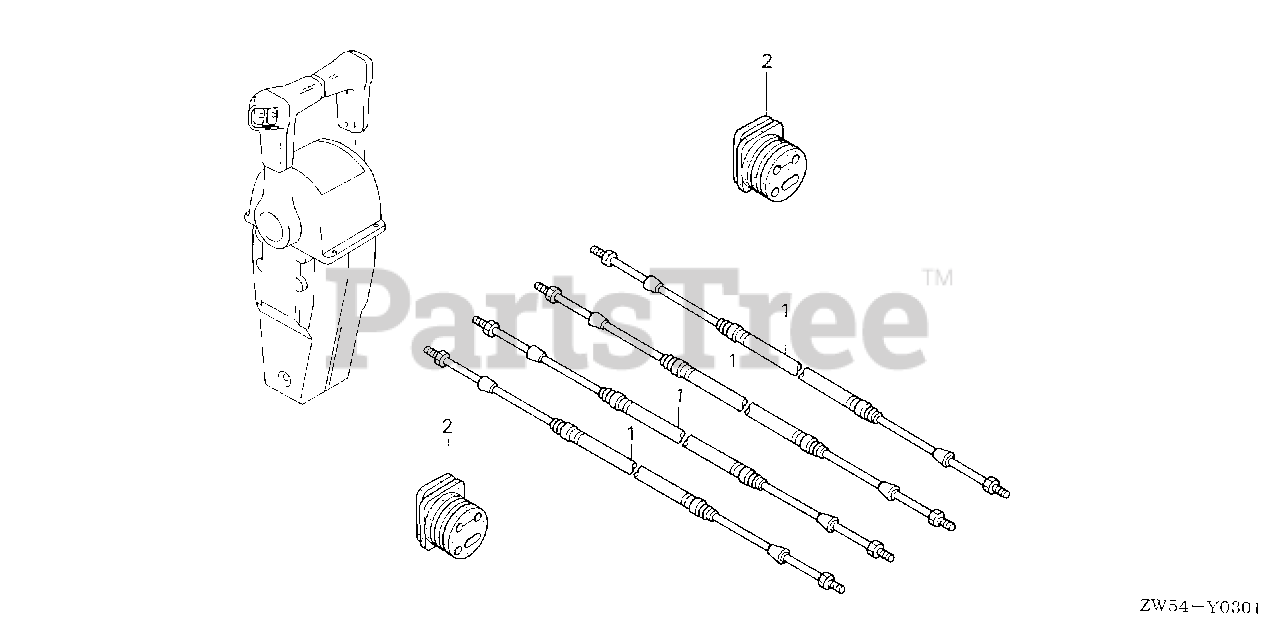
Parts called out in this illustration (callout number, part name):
1	CABLE ASSY., PUSH-PULL
1	CABLE, REMOTE CONTROL (10')
1	CABLE, REMOTE CONTROL (11')
1	CABLE, REMOTE CONTROL (12')
1	CABLE, REMOTE CONTROL (13')
1	CABLE, REMOTE CONTROL (14')
1	CABLE, REMOTE CONTROL (15')
1	CABLE, REMOTE CONTROL (16')
1	CABLE, REMOTE CONTROL (17')
1	CABLE, REMOTE CONTROL (18')
1	CABLE, REMOTE CONTROL (19')
1	CABLE, REMOTE CONTROL (20')
1	CABLE, REMOTE CONTROL (21')
1	CABLE, REMOTE CONTROL (22')
1	CABLE, REMOTE CONTROL (23')
1	CABLE, REMOTE CONTROL (24')
1	CABLE, REMOTE CONTROL (25')
1	CABLE, REMOTE CONTROL (26')
1	CABLE, REMOTE CONTROL (27')
1	CABLE, REMOTE CONTROL (28')
1	CABLE, REMOTE CONTROL (29')
1	CABLE, REMOTE CONTROL (30')
1	CABLE, REMOTE CONTROL (31')
1	CABLE, REMOTE CONTROL (32')
1	CABLE, REMOTE CONTROL (33')
1	CABLE, REMOTE CONTROL (34')
1	CABLE, REMOTE CONTROL (35')
2	GROMMET, CASE (LOWER) (B)
